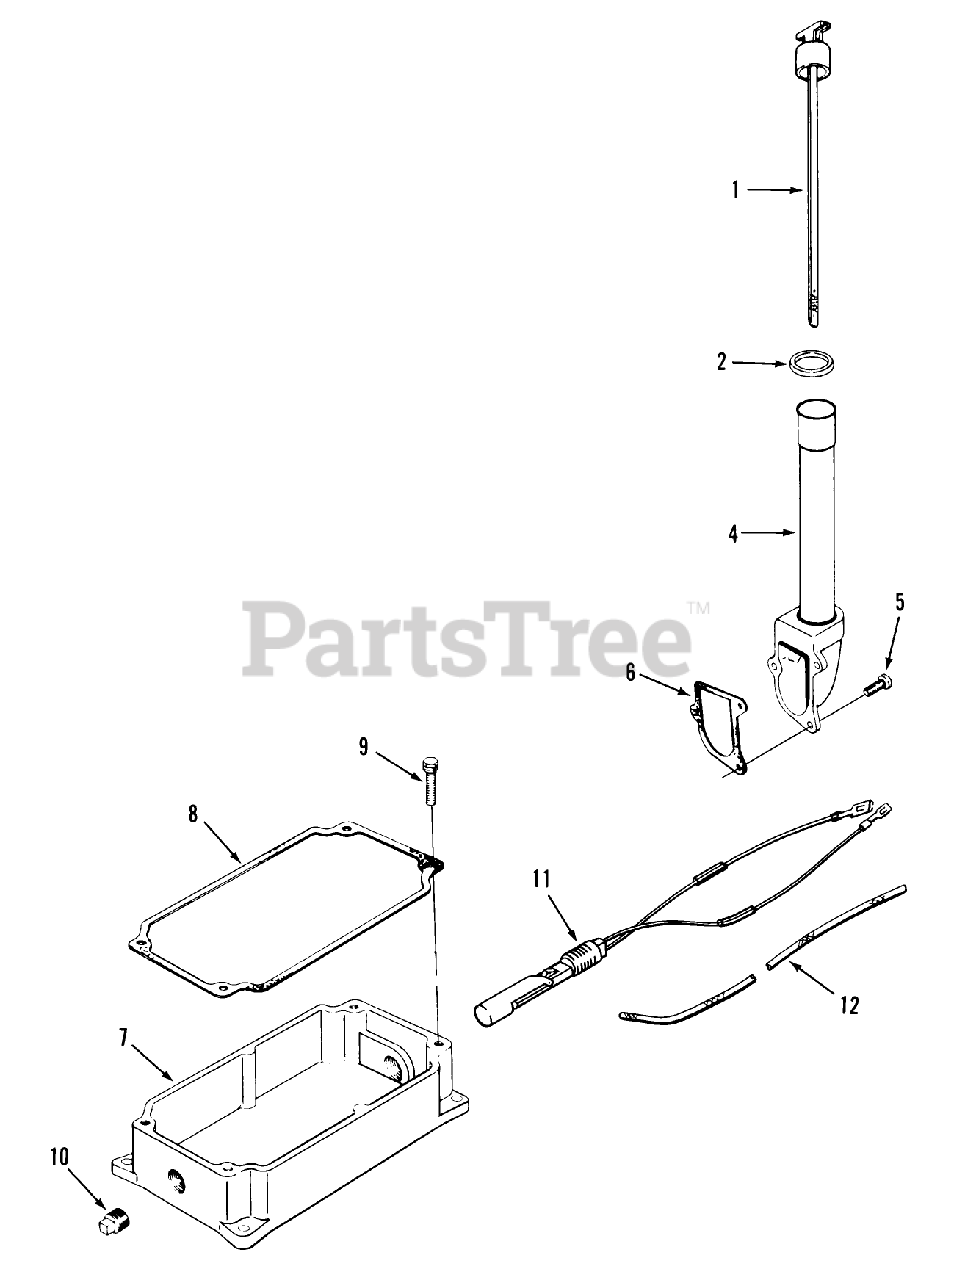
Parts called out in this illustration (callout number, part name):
1	KOHLER 47-038-27
2	KOHLER 41-153-01
4	KOHLER 47-029-06
5	KOHLER X-131-2
6	KOHLER 237064
7	KOHLER 45-199-05
8	KOHLER 235057
9	KOHLER X-159-3
10	KOHLER X-75-10
11	KOHLER 47-099-04
12	KOHLER 25-431-02
